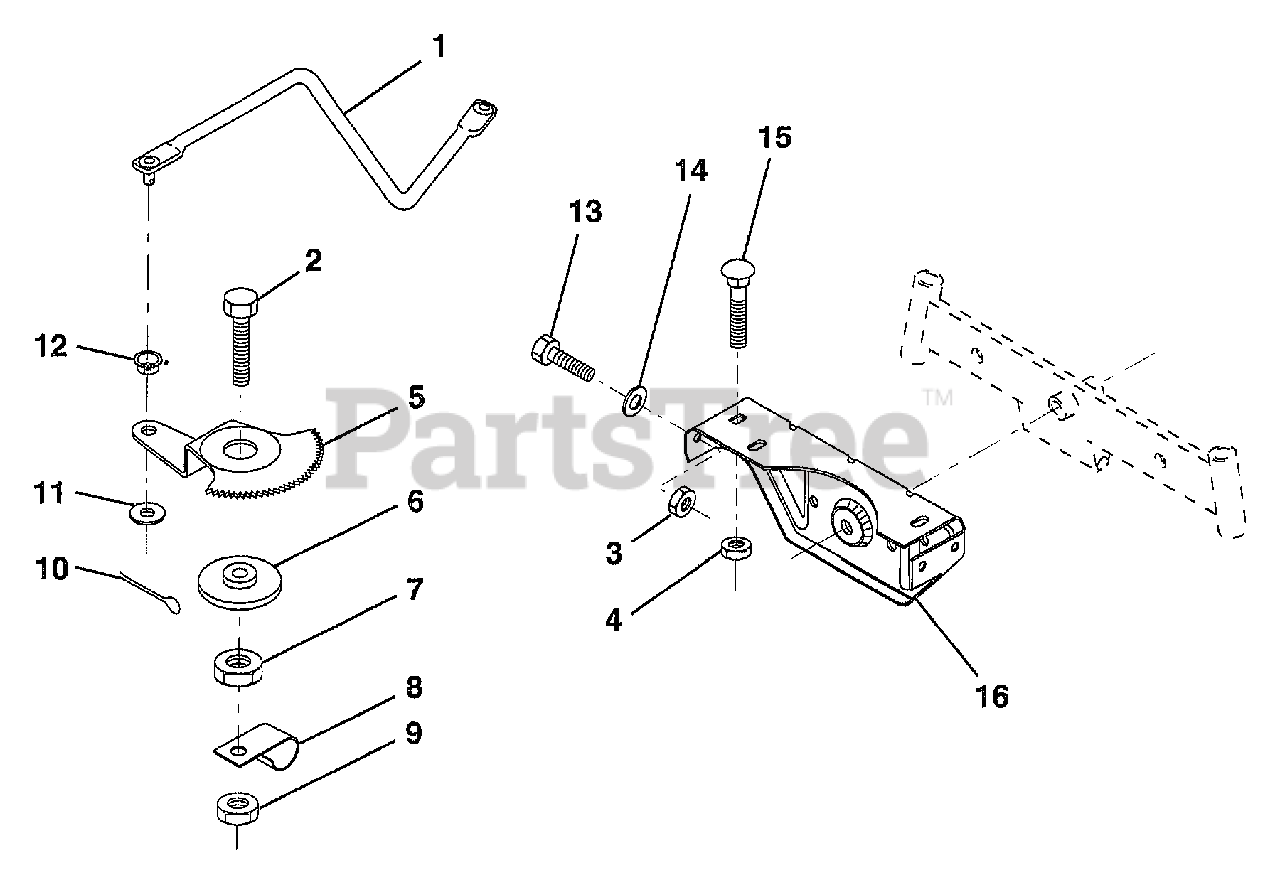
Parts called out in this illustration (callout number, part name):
1	DRAG LINK
2	"BOLT,HEX"
5	GEAR SECTOR
6	BUSHING
7	NUT
8	CLIP INSULATOR
9	NUT LTV
10	COTTER PIN
11	WASHER
12	BUSHING.DRAGLINK
13	BOLT
14	WASHER
15	BOLT
16	SUPT AXLE FRONT
